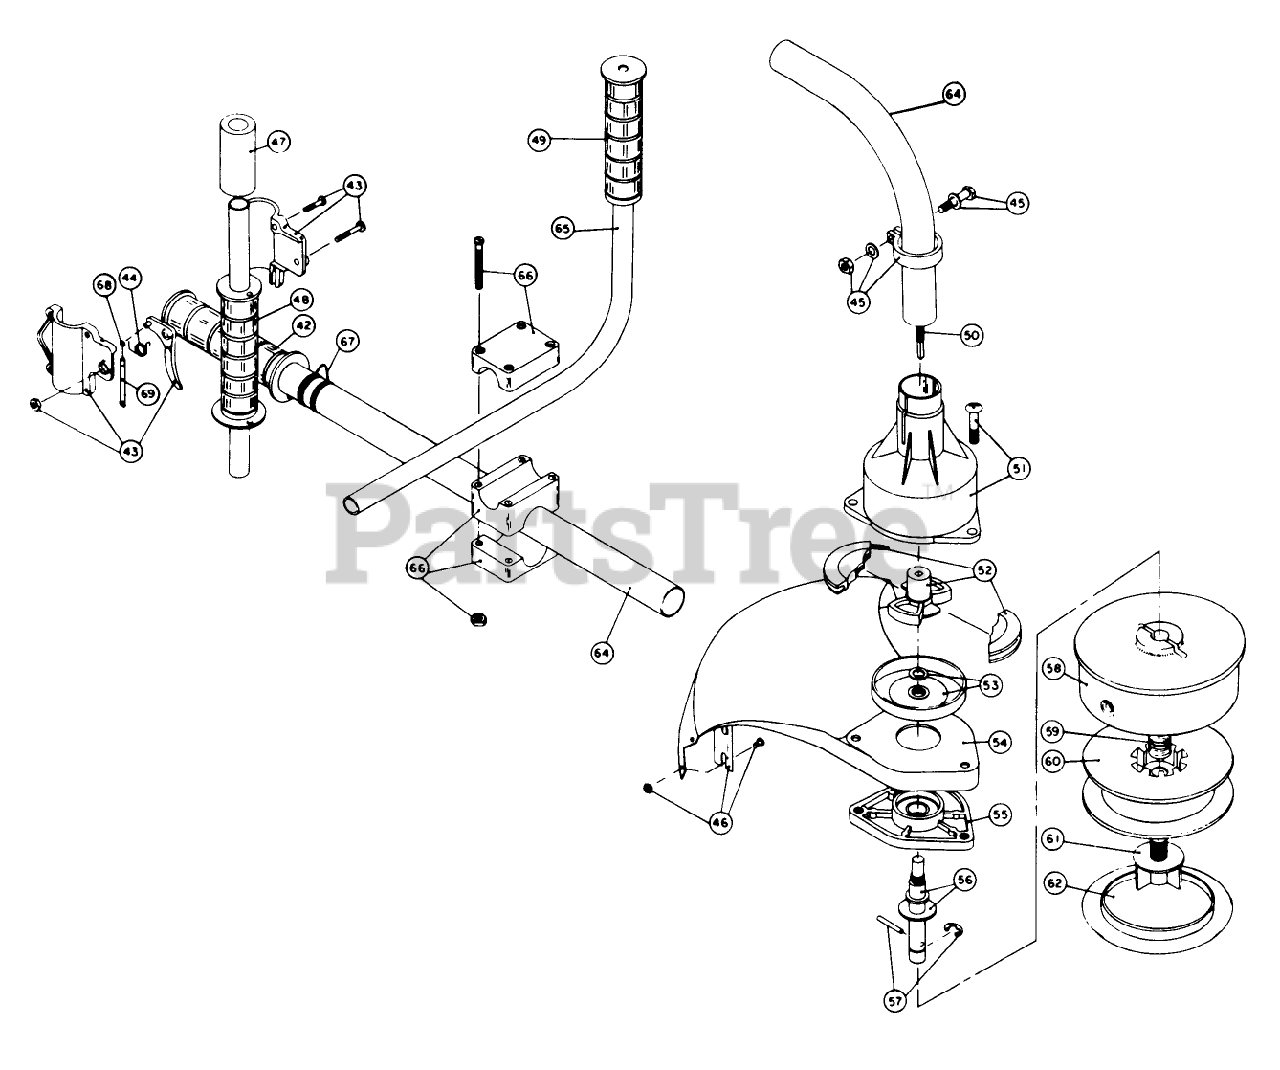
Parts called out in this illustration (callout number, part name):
44	THROTTLE TRIGGER SPRING
46	BLADE ASM
51	CLUTCH HSG ASM
53	Clutch drum assembly
57	Drive pin assembly
61	Spool knob
